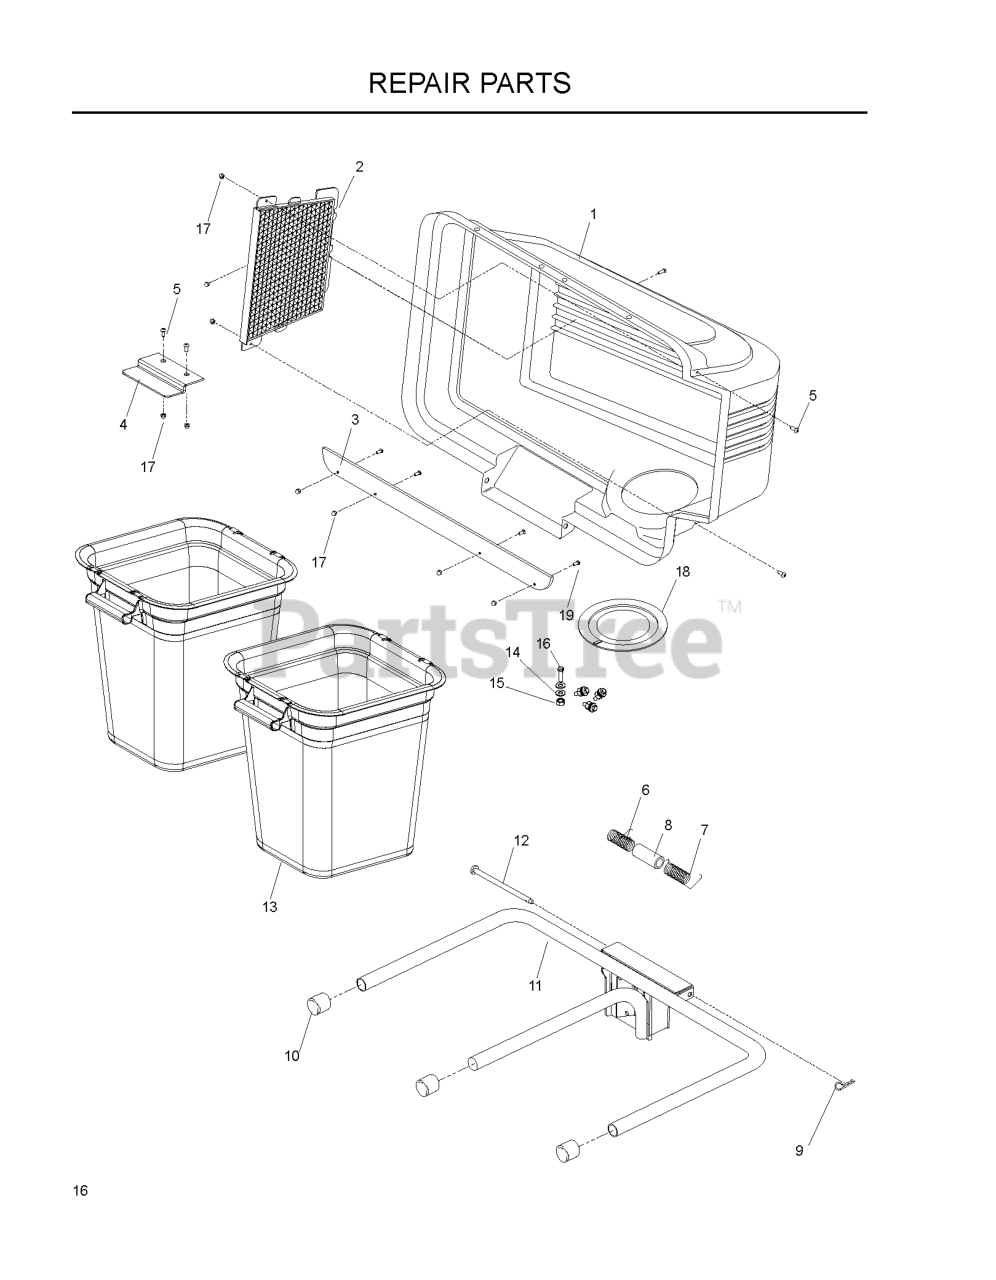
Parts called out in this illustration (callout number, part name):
1	HOOD ASM
2	COVER SCREEN
3	REINFORCING STRIP
4	LATCH CER38
5	SCREW #10-24 X 5/8
6	SPRING COVER LH
7	SPRING COVER RH
8	SPACER COVER
9	RETAINER SPRING
10	TUBING PLUG
11	FRAME, QC42B
12	BAGGER.PIN
13	CONTAINER BAG, SOFT
14	WASHER #10
15	NUT 10-24 NYLOC
16	SCREW 10-24 X 3/4
18	GASKET COVER
